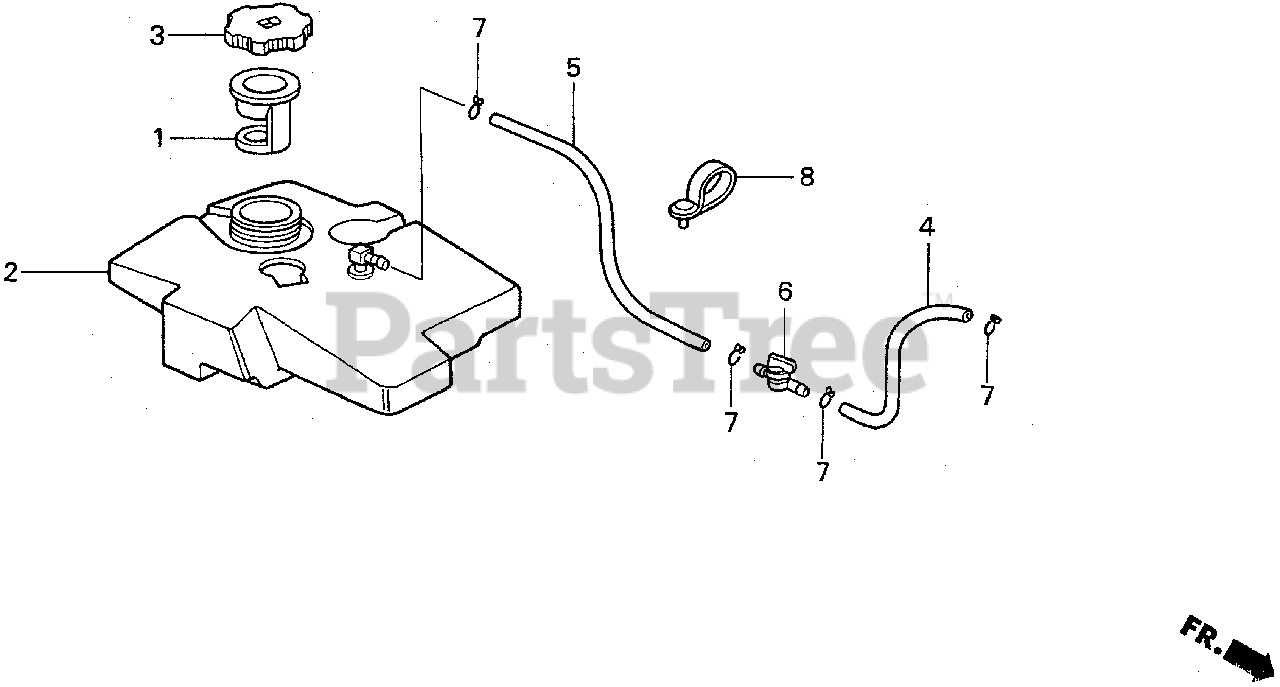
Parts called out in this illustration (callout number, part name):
1	FILTER, FUEL
2	TANK, FUEL
3	CAP ASSY., FUEL TANK
4	TUBE, FUEL
5	TUBE, FUEL
6	VALVE, FUEL SHUT-OFF
7	CLIP, FUEL HOSE
8	RETAINER, QUICK
